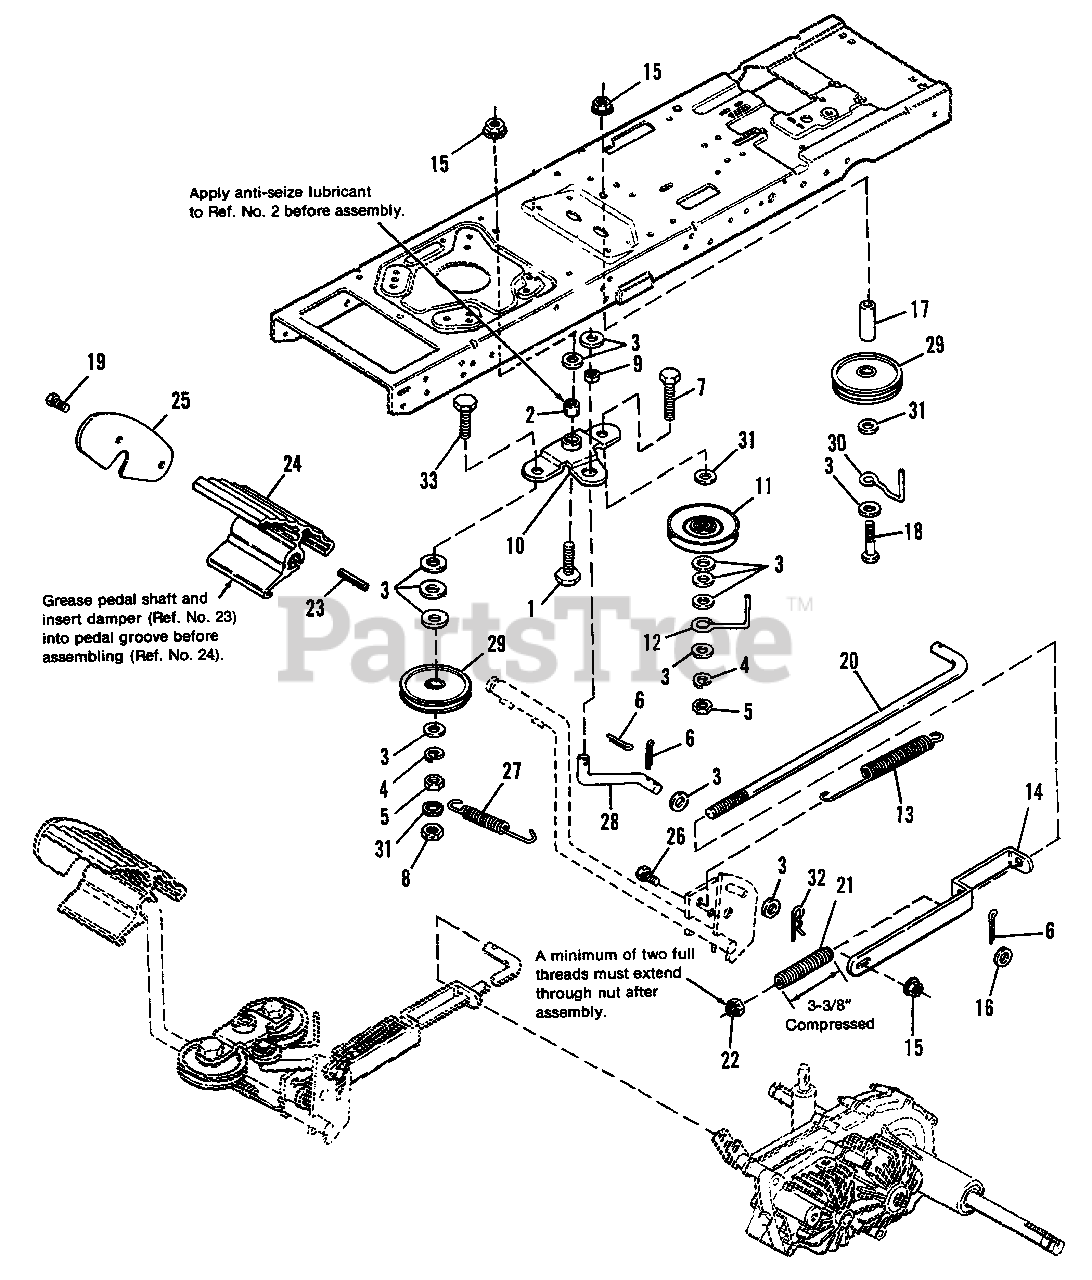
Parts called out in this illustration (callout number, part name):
1	SCREW, Hex, 3/8 16 x 1-1/4, Thin Hd.
3	WASHER, 13/32 x 7/8, 14 Ga.
4	LOCKWASHER, 3/8
5	NUT, Hex, 3/8-16
6	PIN, Cotter
7	CAPSCREW, Hex Hd., 3/8-16 x 1-3/4
8	NUT, Hex, Lock, Jam, 3/8-16
9	BUSHING, Ball
10	ARM ASSY., Clutch
11	PULLEY, "V"
13	SPRING, Tension, Clutch
15	NUT, Hex, Flange Lock, 3/8-16
16	WASHER, 5/16
18	CAPSCREW, Hex, 3/8-16 x 3-1/2
19	SCREW, Taptite, 1/4-20 x 5/8
22	NUT, Hex, Esna, Jam, 5/16-18
23	DAMPER, Rubber
24	PEDAL, Foot
25	PLATE, End
26	CAPSCREW, Hex, 3/8-16 x 3/4
28	LINK, Clutch Arm
29	PULLEY ASSY., Idler, Flat
30	STOP, Belt
31	WASHER, 13/32 x 1, 10 Ga. Plain
32	CUP, Spring
33	CAPSCREW, Hex Hd., 3/8-16 x 2
